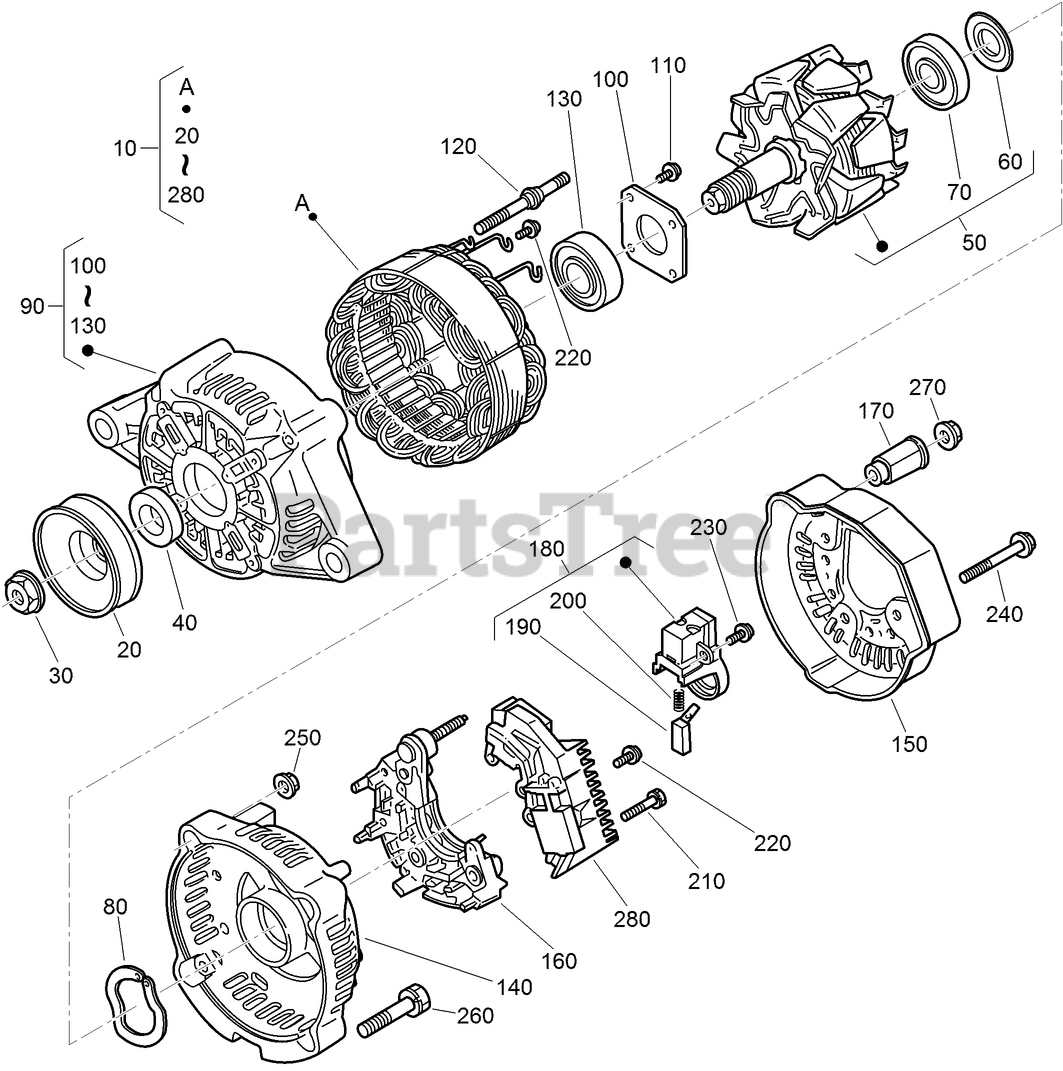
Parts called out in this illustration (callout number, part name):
10	ALTERNATOR ASM
20	PULLEY-DYNAMO
40	COLLAR
50	Rotor ASM
60	COVER-BEARING
70	Bearing-Ball
80	WASHER-THRUST
90	Drive End Frame ASM
100	PLATE-RETAINER
110	SCREW-HEAD, ROUND
120	BOLT-THROUGH
130	Bearing-Ball
140	FRAME-END
150	Cover-End
160	RECTIFIER ASM
170	BUSHING-INSULATION
180	Brush Holder ASM
190	BRUSH
200	SPRING-BRUSH
210	SCREW-HEAD, ROUND
220	SCREW-HEAD, ROUND
230	SCREW-HEAD, ROUND
280	REGULATOR ASM
